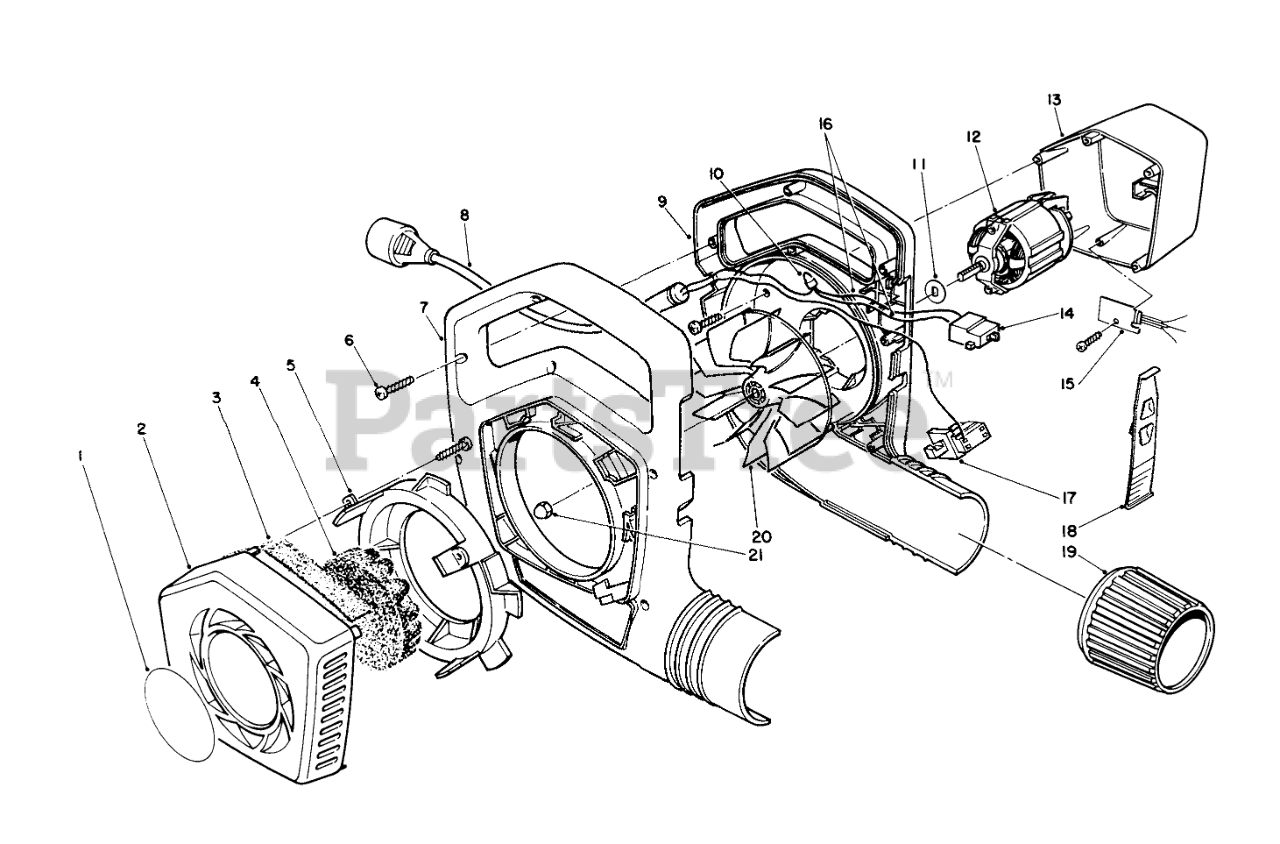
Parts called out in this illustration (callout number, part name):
3	TOP FOAM
4	CENTER FOAM
10	CONNECTOR SCREW
15	DIODE ASSEMBLY
16	WIRE, 3 INCH
17	SWITCH-INTERLOCK
